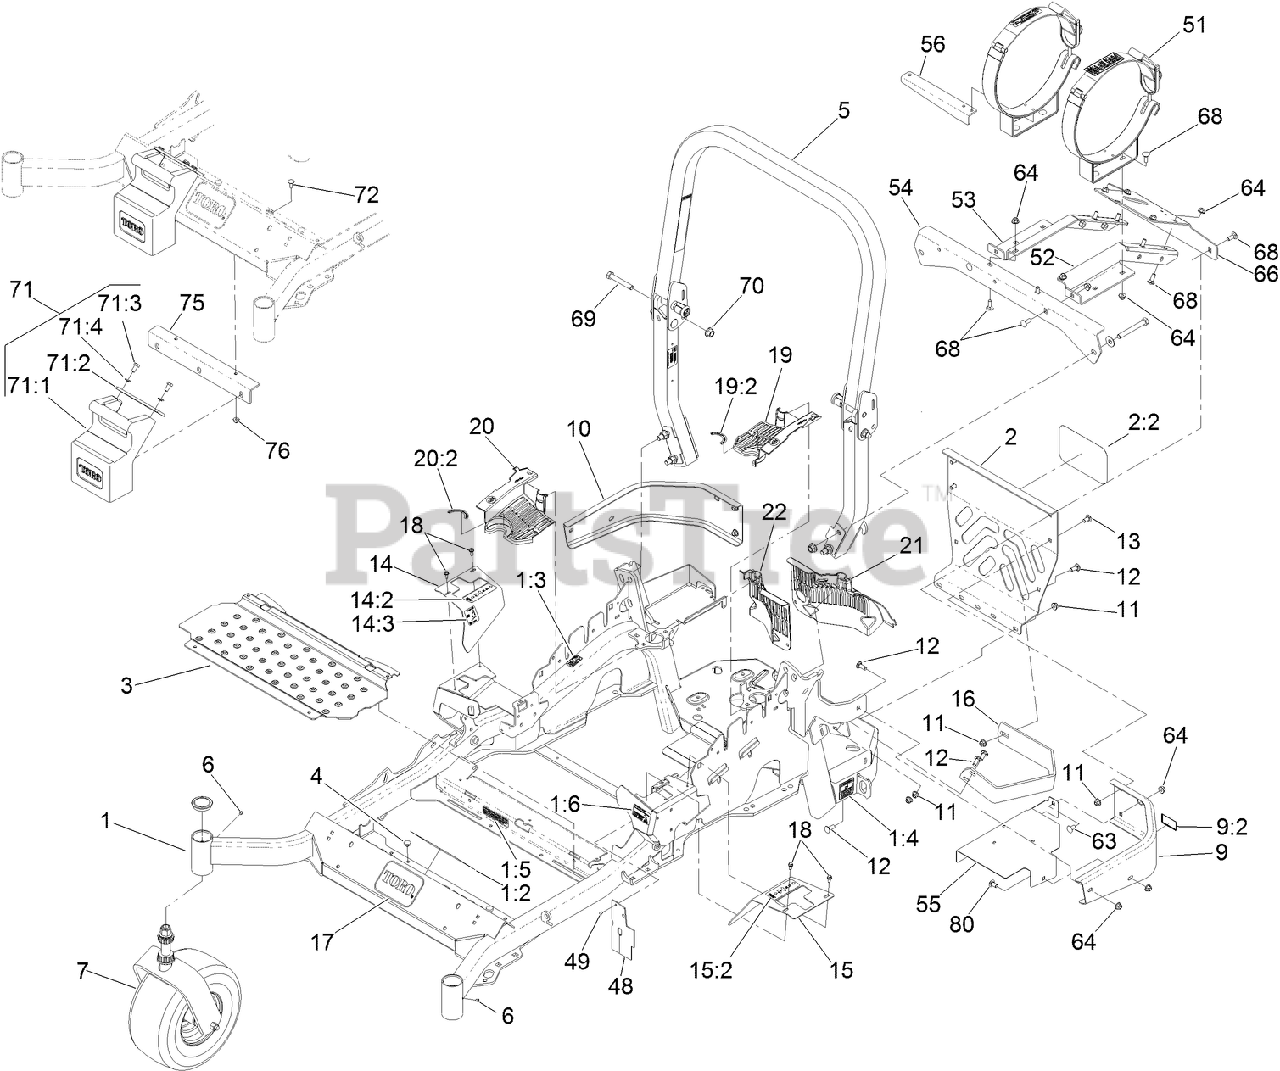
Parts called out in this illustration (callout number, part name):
1	MAIN FRAME ASM
1:2	DECAL-CAUTION
1:3	DECAL-SLOPE
1:4	DECAL-BELT DRIVE
1:5	DECAL-ARRESTER, SPARK
1:6	DECAL-FUEL FILL
2	REAR GUARD ASM
2:2	DECAL
3	FLOORPAN
4	BUMPER
5	ROPS ASM
7	Caster Wheel ASM
9	LH BUMPER ASM
9:2	DECAL-CAUTION
10	BUMPER-RH
11	NUT-HF, NI
12	SCREW-CARR
13	SCREW-CARR
14	RH MOTION CONTROL COVER ASM
14:2	DECAL-MOTION CONTROL
14:3	DECAL-PARK BRAKE
15	LH MOTION CONTROL COVER ASM
15:2	DECAL-MOTION CONTROL
16	GUARD-MUFFLER
17	DECAL
18	SCREW-HWH
19	LH HYDRO GUARD ASM
19:2	DECAL-HYDRO OIL
20	RH HYDRO GUARD ASM
20:2	DECAL-HYDRO OIL
21	GUARD-HYDRO, REAR (LH)
22	GUARD-HYDRO, REAR (RH)
48	DEFLECTOR-AIR FLOW
49	RIVET-POP
51	TANK BRACKET ASM (SET)
52	LH LPG FRAME ASM
53	RH LPG FRAME ASM
54	SUPPORT-LPG FRAME, FRONT
55	PANEL-LPG, AC
56	PLATE-INDEX, LPG TANK
63	SCREW-HH
64	NUT-HF, NI
66	SUPPORT-REAR FRAME, LPG
68	BOLT-CARR
69	SCREW-HH
70	NUT-LOCK
71	WEIGHT ASM
71:1	WEIGHT-43 LB
71:2	TAB-SUPPORT, WEIGHT
71:3	SCREW-HH
71:4	WASHER-LOCK
72	SCREW-CARR
75	BRACKET-MOUNT, WEIGHT
76	NUT-HF, NI
80	SCREW-CARR
